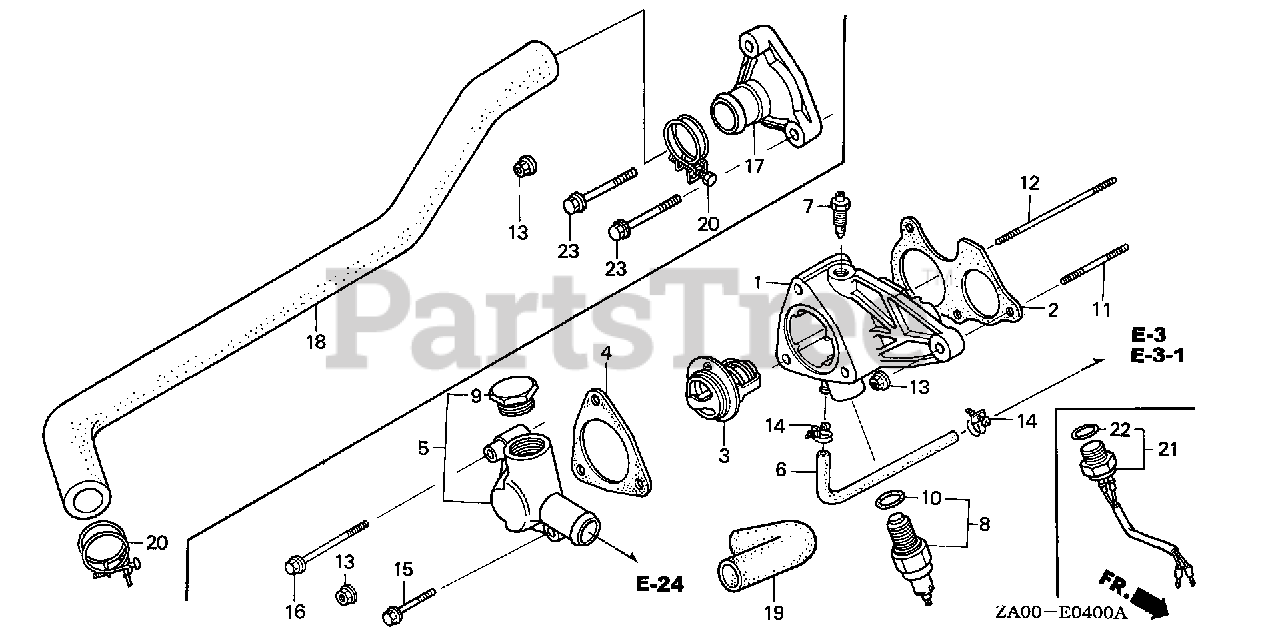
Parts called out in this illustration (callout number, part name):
1	CASE, THERMOSTAT
2	GASKET, GOVERNOR CASE
3	THERMOSTAT ASSY.
4	GASKET, THERMOSTAT COVER
6	HOSE, WATER BYPASS
7	BOLT, BREATHING WATER
11	BOLT, STUD (6X25)
12	BOLT, STUD (6X60)
13	NUT, FLANGE (6MM)
14	CLIP, TUBE (A13)
17	COVER, THERMOSTAT
18	HOSE, WATER (UPPER)
20	CLIP, WATER HOSE
21	SWITCH, SOLENOID THERMOSTAT
22	O-RING (15.5X1.4)
23	BOLT, FLANGE (6X60)
